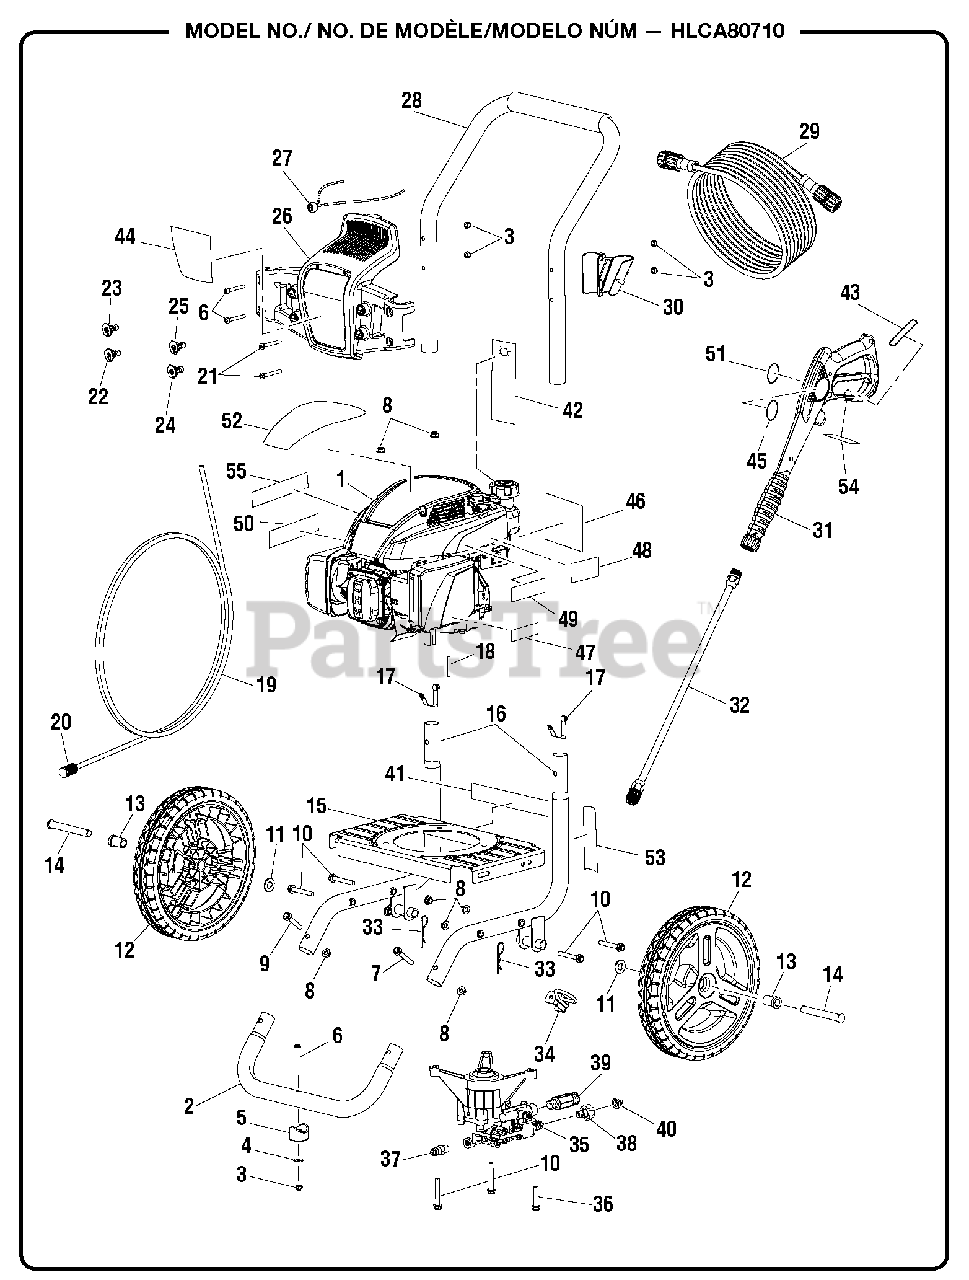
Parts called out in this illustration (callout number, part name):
1	163 cc Engine
2	Front Frame
3	Lock Nut (1/4-20)
4	Washer (1/4 in.)
6	Screw (1/4-20 x 1.85 in., Torx)
7	Bolt (M8 x 50 mm)
8	Lock Nut (M8 x 1-1/4 in.)
9	Bolt (M8 x 45 mm)
10	Bolt (M8 x 55 mm)
11	Washer (1/2 in.)
12	Wheel (12 in. x 2 in.)
13	Axle Sleeve
15	Engine Plate
16	Main Frame Assembly (Inc. Key No. 17)
17	Lock Button w/Spring Clip
18	Output Shaft Key
19	Injection Hose
21	Screw (1/4-20 x 2 in., Torx)
22	40deg Nozzle
23	0deg Nozzle
24	25deg Nozzle
25	Detergent Nozzle
26	Storage Holder (4 Nozzle)
27	Bungee Cord and Bead Assembly
28	Handle Assembly
29	High Pressure Hose (25 ft.)
30	Upper Wand Holder
31	Trigger Handle Assembly
32	Spray Wand
33	Hitch Pin
34	Lower Wand Holder
35	Pump (Incl. Key Nos. 38-40)
36	Bolt (M8 x 40 mm Hex Hd.)
37	Thermal Release Valve
38	Inlet Tube
39	Outlet Tube
40	Filter Screen
41	Data Label
42	Hang Tag (Engine Oil Fill)
43	Wand Label (Max Rating)
44	Performance Label
45	Trigger Handle Warning Label
46	Warning Label
47	Engine Quick Start Label
48	Switch Label (Engine Off)
49	Warning Label (Combustion)
50	Hot Surface Label
51	Wand Label
52	Engine Label
53	Pump Quick Start Label
54	Warning Label (French/Spanish)
55	EMC Label
